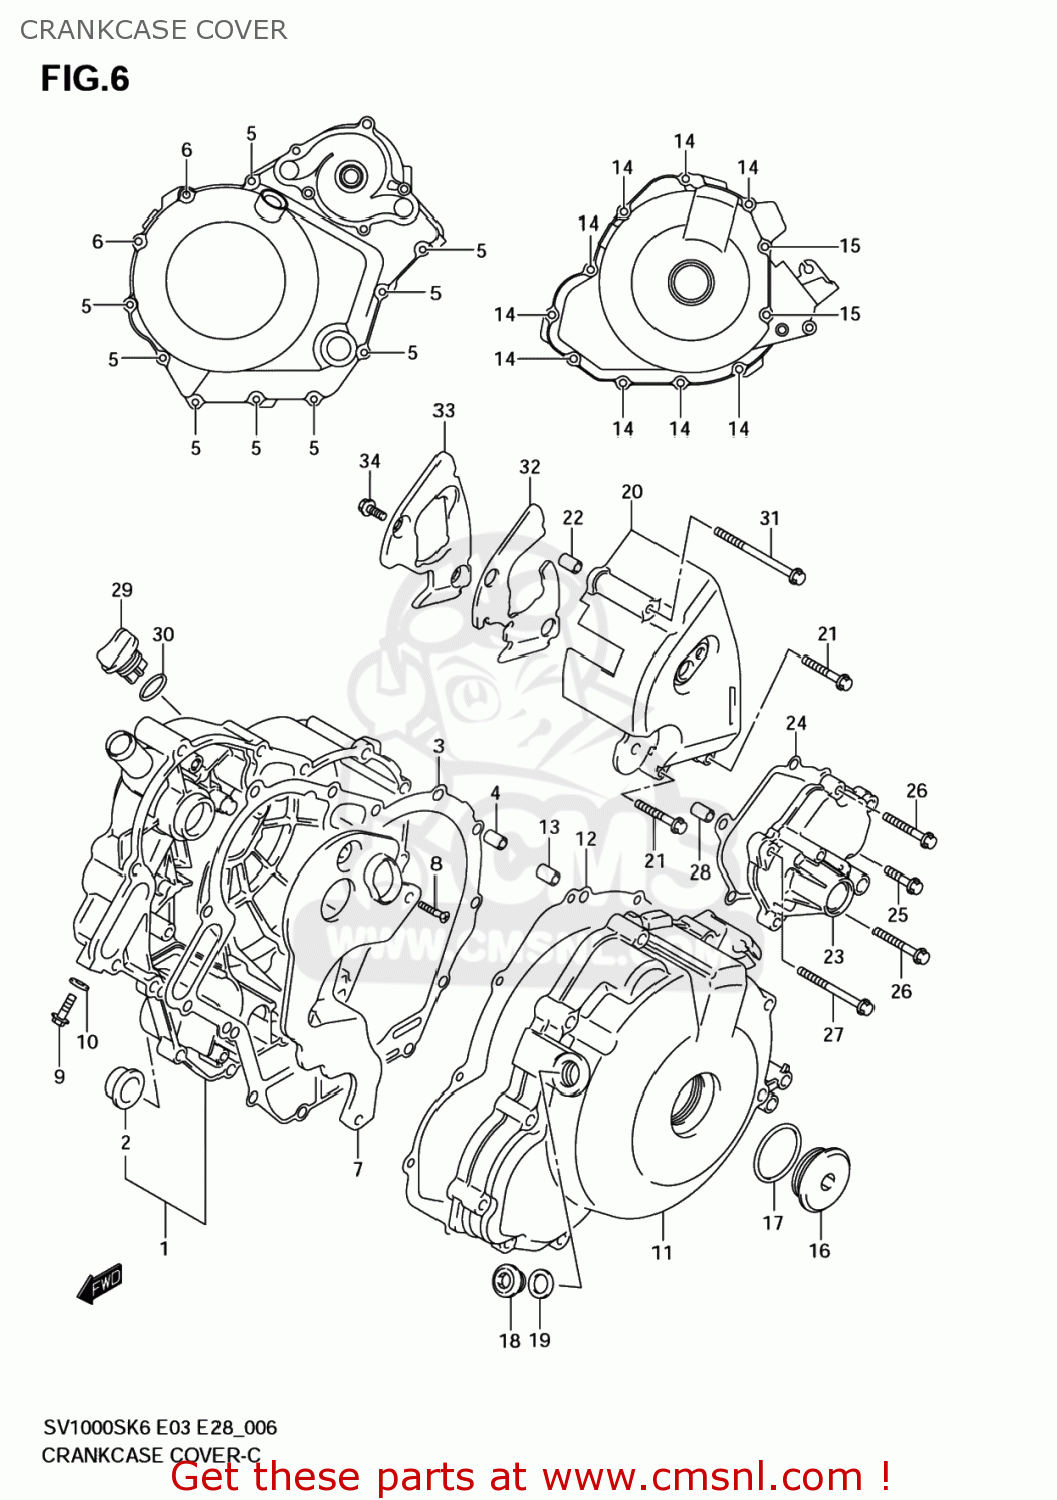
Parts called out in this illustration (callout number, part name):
1	COVER COMP,CLU
2	LENS,OIL LEVEL CHECK
3	GASKET,CLUTCH COVER (NAS)
4	PIN
5	BOLT(6X30)
6	BOLT(6X75)
7	SEPARATOR,OIL
8	SCREW
9	BOLT
10	GASKET(6.4X11.5X0.8) (NAS)
11	COVER,MAGNETO
12	GASKET,MAGNETO COVER (NAS)
13	PIN
14	BOLT(6X35)
15	BOLT(6X70)
16	PLUG(SILVER)
17	O RING(D:3.1,ID:32.7)
18	PLUG,14X12
19	GASKET(13.8X18.8X4.8) (NAS)
20	COVER,ENGINE SPROCKET
21	BOLT(6X35)
22	PIN
23	COVER,GEAR SHIFT
24	GASKET,GEAR SHIFT COVER (NAS)
25	BOLT(6X105)
26	SCREW
27	BOLT
28	PIN
29	PLUG,ENGINE OIL FILLER
30	O RING(D:3.1,ID:16.8)
31	BOLT(6X80)
32	DAMPER,ENG SPROCKET COVER
33	PLATE,ENG SPROCKET COVER
34	BOLT(6X12)
